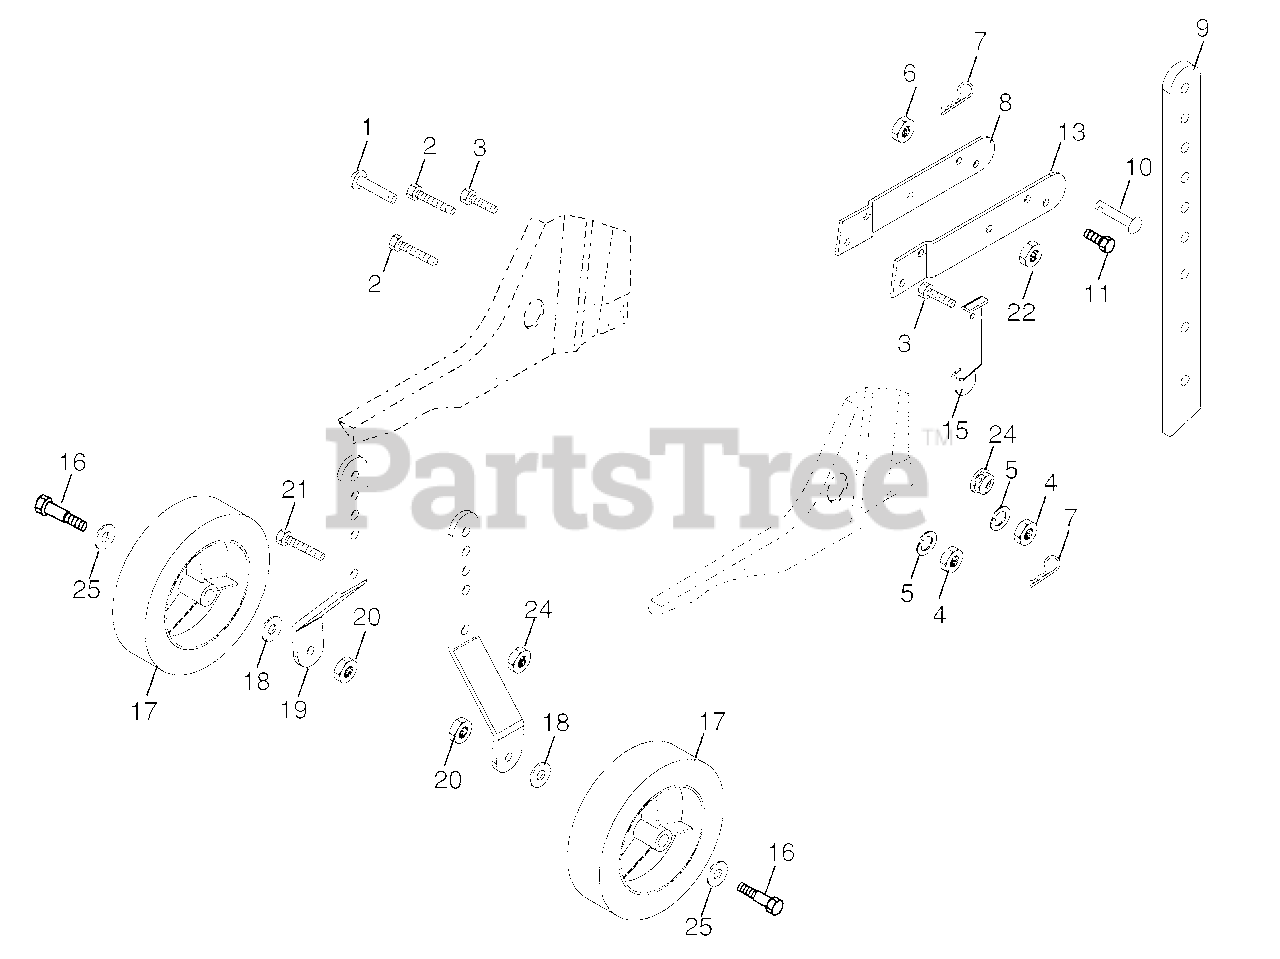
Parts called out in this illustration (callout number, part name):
1	Pin, Clevis
2	Bolt, Hex Head 5/16-18 x 1-1/4
3	Bolt, Hex Head 5/16-18 x 3/4
4	Nut, Hex 5/16-18
5	Washer, Lock 5/16
6	Locknut, Washer Insert 3/8-16
7	Clip, Hairpin
8	Support, Depth Stake, R.H.
9	Stake, Depth
10	Pin, Clevis
11	Bolt, Hex Head 3/8-16 x 1-3/4
13	Support, Depth Stake, L.H.
15	Spring, Stake
16	Bolt, Shoulder
17	Wheel
18	Washer 13/32 x 13/16 x 11 Gauge
19	Bracket, Wheel
20	Nut, Hex, Crownlock 3/8-16
21	Bolt, Hex Head 5/16-18 x 1
22	Locknut, Washer Insert 5/16-18
24	Nut, Hex, Flangelock
25	Washer
